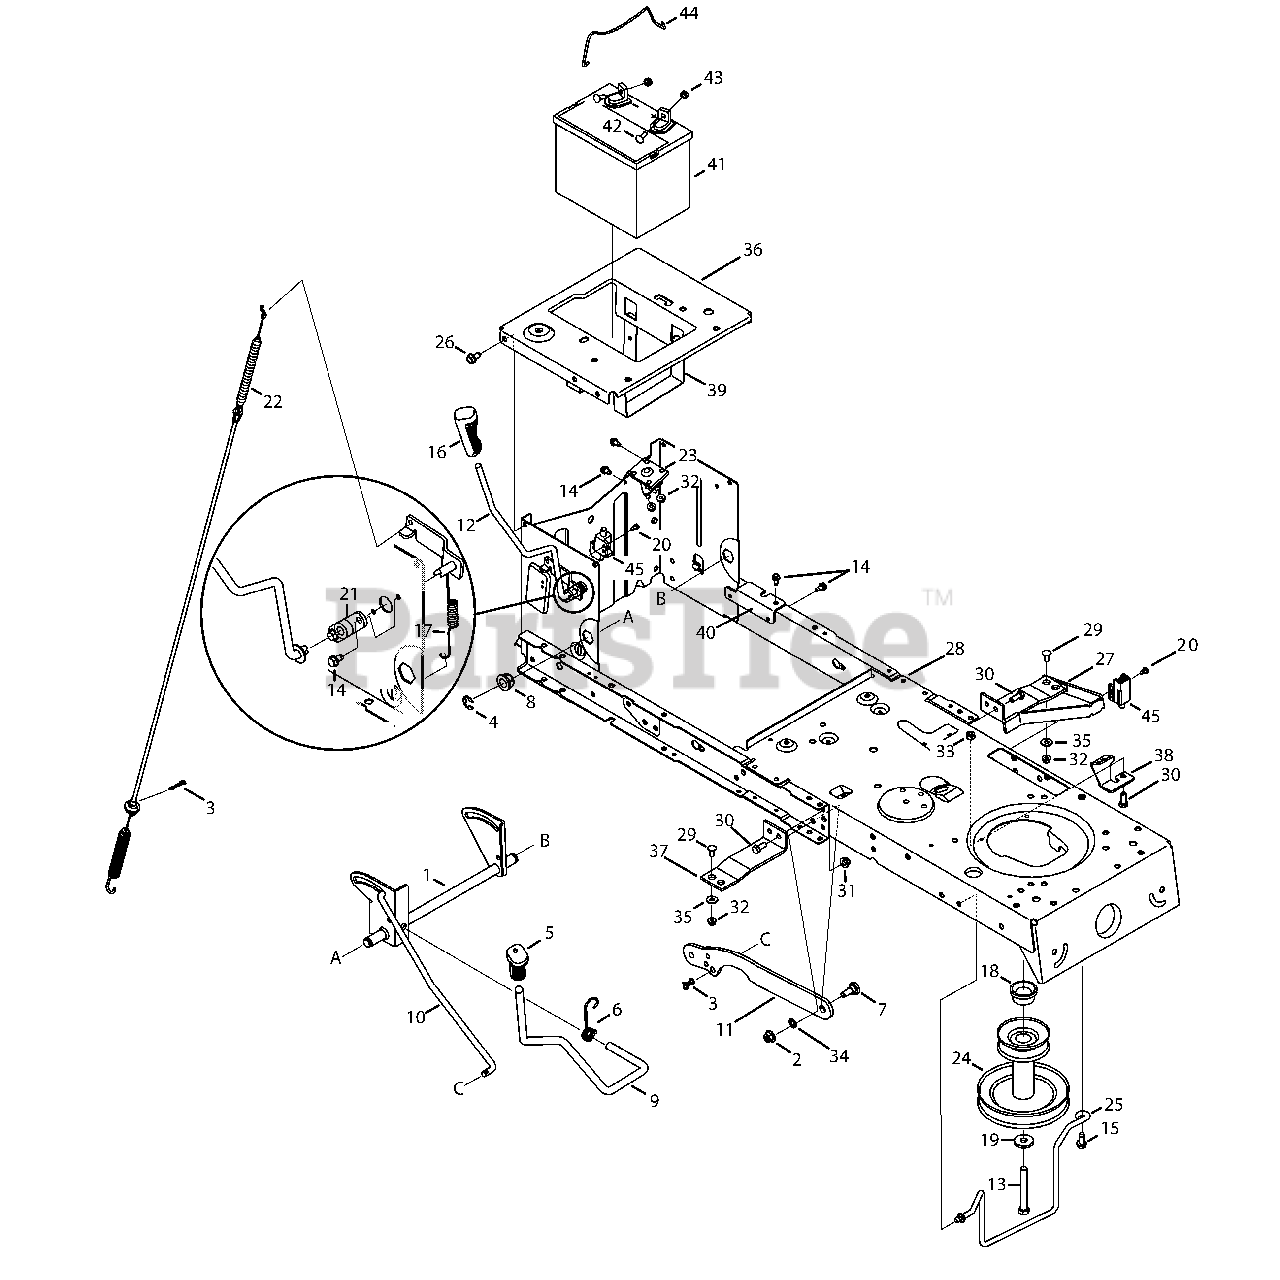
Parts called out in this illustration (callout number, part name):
1	Shaft, Lift
2	Nut, Hex Flange Insert Lock, 3/8-16
3	Bow-Tie Pin, 91, RH
4	E-ring, .625 Shaft
5	Grip, Handle
6	Spring, Lift Handle Torsion
7	Bolt, Shoulder, .500 x .270, 3/8-16
8	Bearing, Hex Flange,
9	Handle, Lift
10	Lift Rod, 13.68
11	Arm, Deck Lift RH
12	PTO Handle Assembly
13	Screw, Hx. Hd., 7/16-20 x 3.25
14	Screw, Hd. Tapp, 1/4-20 x .5
15	Screw, Hd. Tapp, 5/16-18 x .75
16	Handle Grip
17	PTO Spring, Extension
18	Spacer
19	Washer, Flat, .450 x .250 x .164
20	Shoulder Screw, #10-32 x .500
21	PTO Bearing
22	Deck Engagement Cable
23	12v. Solenoid
24	Engagement Pulley
25	Belt Keeper Rod Assembly
26	Screw, Hd. Tapp, 5/16-18 x .75
27	Support Bracket Assembly
28	Rider Frame Assembly
29	Carriage Screw, 1/4-20 x .62
30	SCREW 5/16-18 x .75 GR5
31	Nut, Flange Insert Lock 5/16-18
32	Nut, Hex Flange Insert Lock, 1/4-20
33	Hexlock Nut, 5/16-18
34	Washer, Flat, .385 x .62 x .063
35	Flat Washer, .28 x .74 x .063
36	Seat Bracket Frame
37	Running Board Bracket
38	Frame Support Bracket
39	Battery Bracket
40	Frame Brace Bracket
41	Battery
42	Screw, Shoulder, .250 x .150
43	Nut, Sems, 1/4-20
44	Battery Rod
45	Interlock Switch
